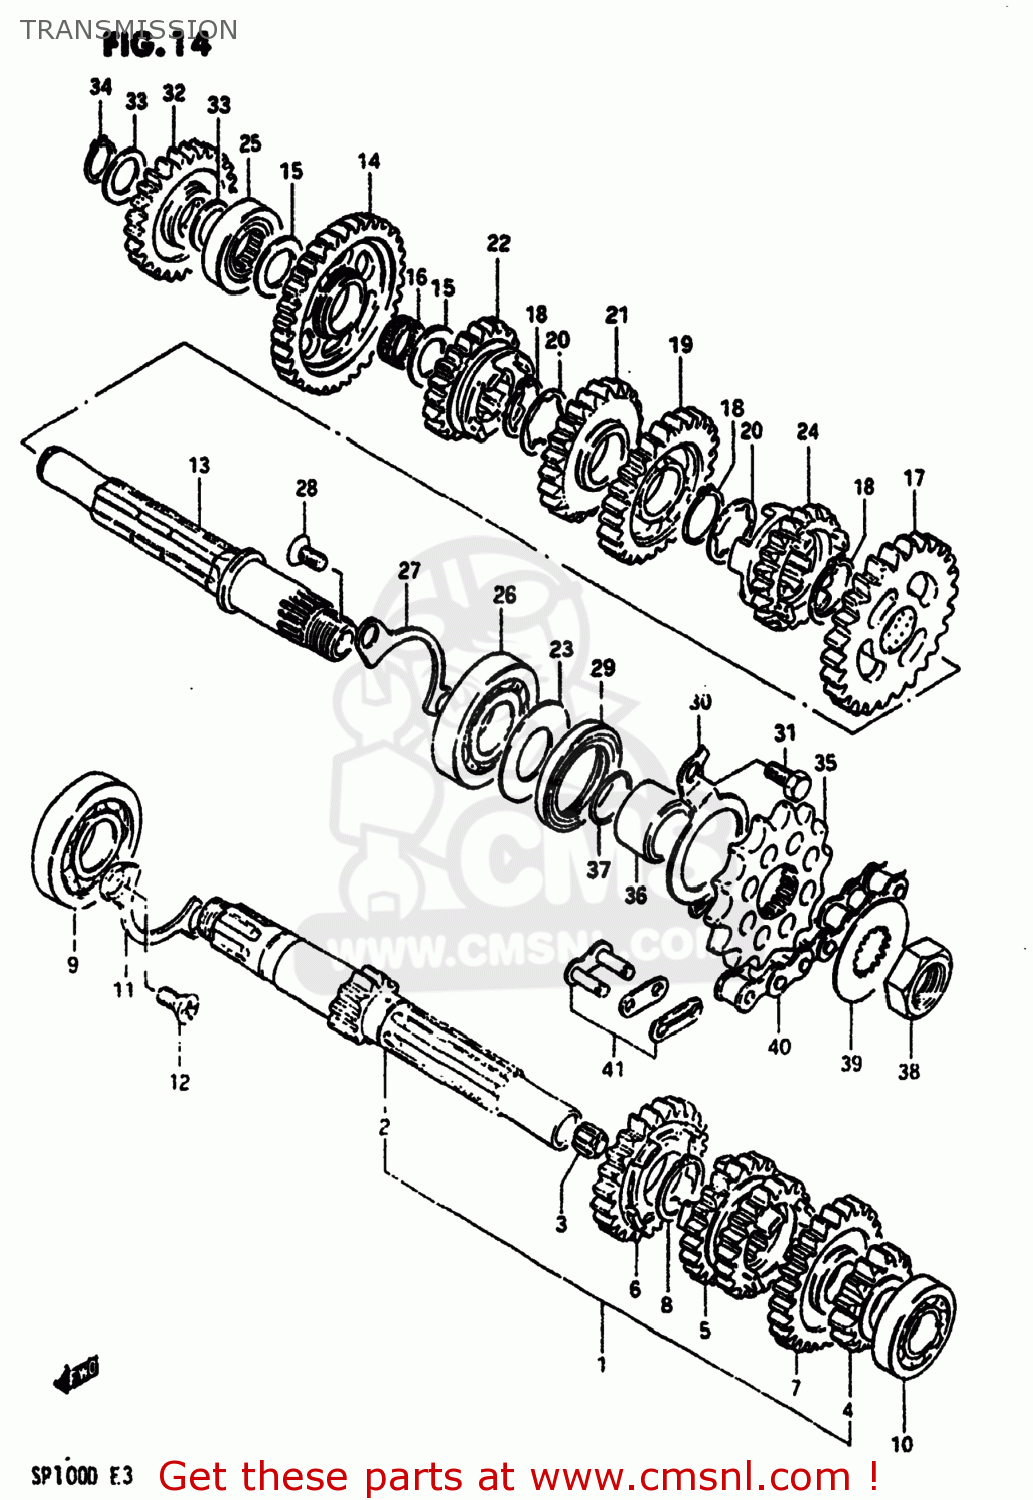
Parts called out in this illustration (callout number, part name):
1	SHAFT,COUNTER
2	SHAFT,COUNTER
3	BUSHING
4	GEAR,SECOND DRIVE
5	GEAR,THIRD & FOURTH DRIVE,N
6	GEAR,FIFTH DRIVE
7	GEAR,SIXTH DRIVE
8	CIRCLIP
9	BEARING
10	BEARING, LH
11	RETAINER,DRIVE SHAFT BEARING
12	SCREW
13	SHAFT,DRIVE
14	GEAR,FIRST DRIVEN
15	WASHER
16	BEARING(15X19X7.8)
17	GEAR,SECOND DRIVEN
18	CIRCLIP
19	GEAR,THIRD DRIVEN
20	WASHER,LOCK
21	GEAR,FOURTH DRIVEN
22	GEAR,FIFTH DRIVEN
23	WASHER,OIL SEALING
24	GEAR,SIXTH DRIVEN
25	BEARING(15X33X12)
26	Bearing
27	RETAINER,DRIVE SHAFT BEARING
28	SCREW
29	SEAL,OIL(27X40X6)
30	PLATE,DRIVESHAFT OIL
31	BOLT
32	GEAR,KICK STARTER IDLE(NT:26)
33	WASHER
34	CIRCLIP,15MM
35	SPROCKET,ENGINE(NT:13)
36	SPACER
37	O RING(D:2.4,ID:19)
38	NUT
39	WASHER,LOCK
40	CHAIN ASSEMBLY,DRIVE
41	JOINT,CHAIN
